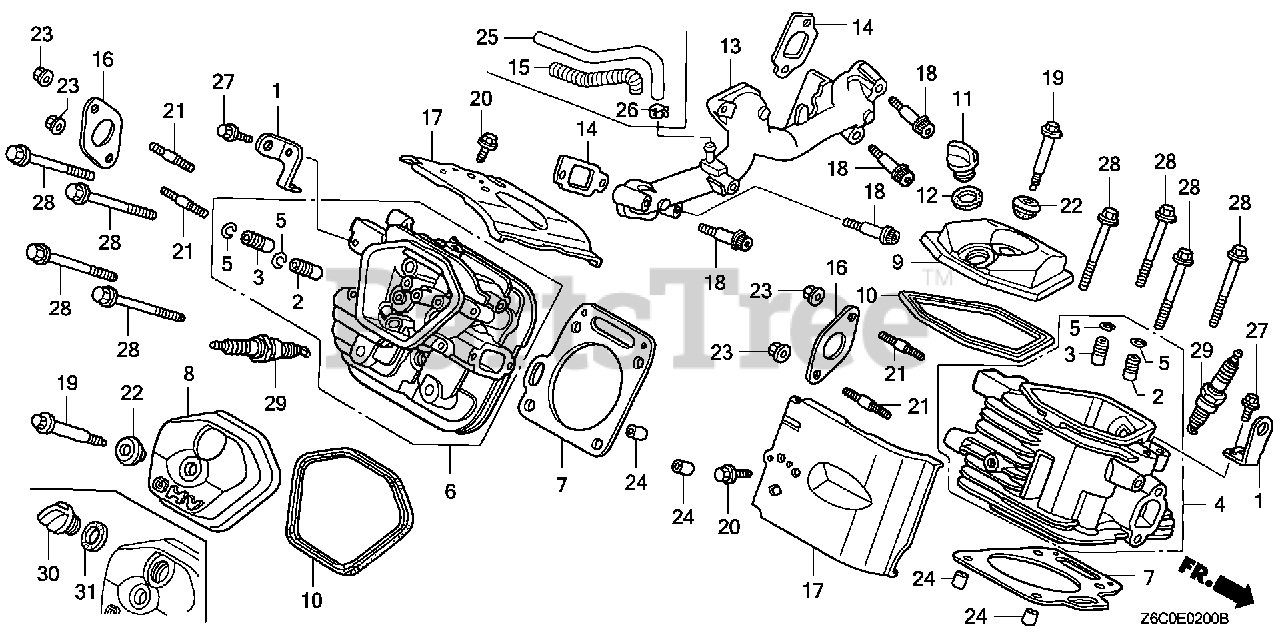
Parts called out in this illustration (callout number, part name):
1	HANGER, ENGINE
2	GUIDE, VALVE (OS)
3	GUIDE, EX. VALVE (OS)
4	CYLINDER HEAD (#1)
5	CLIP, VALVE GUIDE
6	CYLINDER HEAD (#2)
7	GASKET, CYLINDER HEAD
8	COVER, HEAD
9	COVER, HEAD FILLER
10	GASKET, CYLINDER HEAD COVER
11	CAP, OIL FILLER
12	GASKET, OIL FILLER CAP
13	MANIFOLD, IN.
14	GASKET, IN. MANIFOLD
16	GASKET, EX. PIPE Use up to Engine SN 2949254.
16	GASKET, EX. PIPE (WACKER)
17	SHROUD, HEAD
18	BOLT, SOCKET (8X45)
19	BOLT, HEAD COVER
20	BOLT, FLANGE (6X14)
21	BOLT, STUD (8X22)
22	WASHER, HEAD COVER
23	NUT, FLANGE (8MM)
24	PIN A, DOWEL (12X20)
27	BOLT, FLANGE (8X20) Use up to Engine SN 1609606.
28	BOLT, FLANGE (10X80)
29	SPARK PLUG (BPR2ES) (NGK)
29	SPARK PLUG (J14CR-U)
29	SPARK PLUG (ZGR4A) (NGK)
